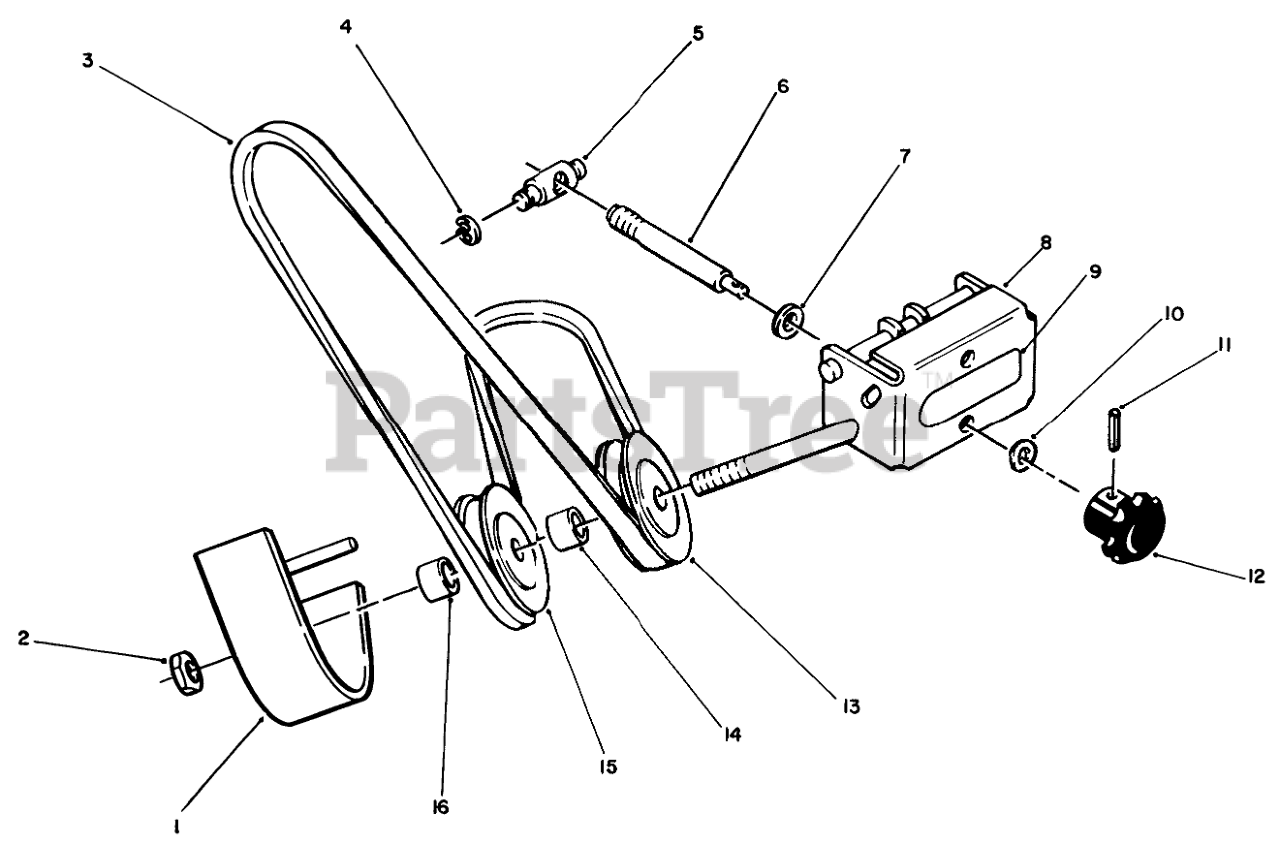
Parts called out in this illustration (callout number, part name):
1	Belt Cover
2	Nut
3	V-BELT
4	RING-RETAINING
5	TRUNNION-DOUBLE
6	ROD ADJ
7	Washer
8	Front Support
9	Decal-Attac-O-Matic
10	WASHER-SPRING
11	PIN-ROLL
12	KNOB-ADJUSTMENT
13	Pulley-V
14	SPACER
15	PULLEY-FLAT IDLER
16	SPACER-OUTER
